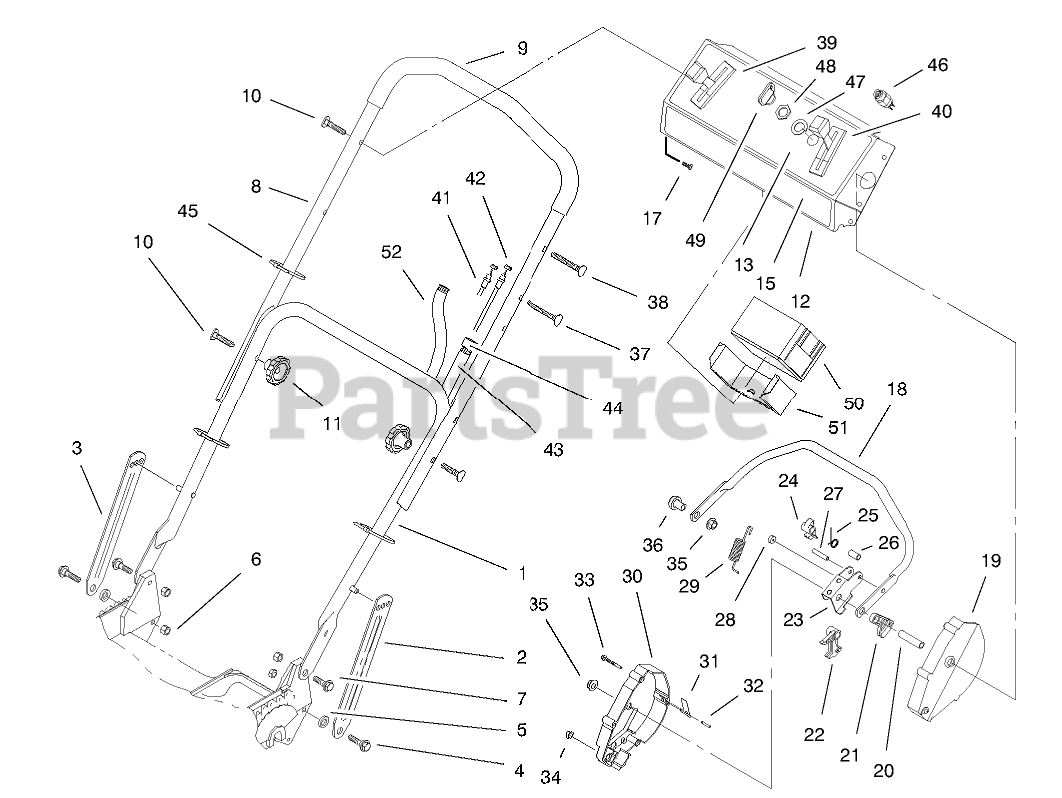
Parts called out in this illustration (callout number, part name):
1	ASM-Handle
2	Latch-Handle
3	Latch-Handle
4	SCREW-SHOULDER
5	SPACER
6	NUT-LOCK, NI
7	SCREW-SHOULDER
8	Handle-Upper
9	Grip-Foam
10	SCREW-HANDLE
12	Panel-Control (Incl. Ref. #13)
13	DECAL - INSTRUCTION
15	DECAL - FRT PANEL
17	SCREW-TAP
18	Bar-Control
19	HOUSING-CONTROL, LH
20	TUBING-SPACER
21	LEVER-TRACTION
22	ROCKER
23	LEVER-CABLE
24	HOOK-CONTROL
25	SPRING-TORSION
26	SPACER
27	PIN-ROLL, SLOTTED
28	WASHER-NYLON
29	SPRING-DETENT
30	Housing-Control
31	SPRING-LEAF
32	PIN-INSERT
33	SCREW-HWHTF
34	NUT-LOCK NI
35	NUT-LOCK NI
36	SPACER-SUPPORT
37	SCREW-HANDLE
38	OBS MATERIAL EXCEPT FOR SERVICE
39	CONTROL-SPEED, GROUND
40	THROTTLE CONTROL
41	CLUTCH CABLE
42	TRACTION CABLE
43	CONTROL CABLE COVER
44	FITTING-RING
45	TIE-CABLE
46	Switch-Starter (Incl. Ref. #47 & 48)
47	WASHER-TOOTH, INTERNAL
48	NUT-HH
49	KEY-IGNITION
50	BATTERY ASSEMBLY
51	Retainer-Battery
52	Harness-Wire
